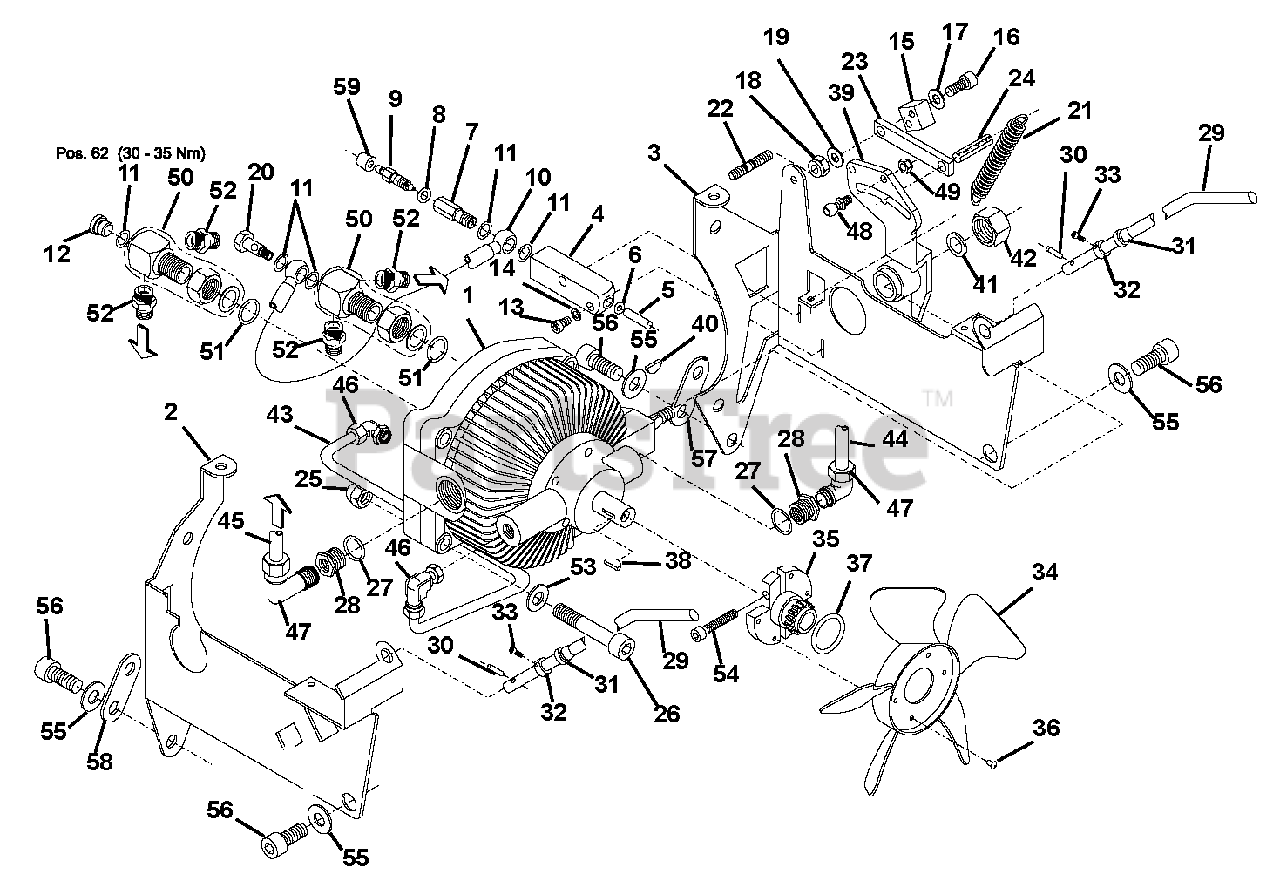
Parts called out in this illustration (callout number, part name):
1	Hydraulic Pump
2	Bracket, Left Hydrostat
3	Bracket, Right Hydrostat
4	Bushing, Guide
6	O-Ring, D3770 6,07 x 1,78
7	Bolt, Hollow Special
8	O-Ring, D3770 6.00 x 3.00
10	Hydraulic Hose
11	Ring, Gasket
12	Plug, Drain D910 Right 1/8"
13	Screw, Cylinder, D912 Metric 4 x 12
14	Washer, Form Metric 4.1/10.2 x 1.0
16	Screw, D912 Metric 6 x 12
17	Washer, M6
18	Nut, Lock, D985 M6
19	Washer, D125 6,4 x 12 x 1,6
20	Bolt, Hallow
21	Spring, Tension, 1.2/10.8 x 62
22	Stud, D939 Metric 6FO x 16
24	Pin, Heavy
25	Cap Nut, D1587 M10
26	Screw, D912 M10 x 60
27	O-Ring, D3770 199,00 x 2,40
28	Connector
29	Control Rod
30	Pin, Heavy, D1481 4 x 20
32	Adjustment Ring
33	Screw, Cylinder, D912 Metric 4 x 5
36	Rivet, Blind
37	O-Ring, D3770 28,00 x 5,00
38	Key, D6888 3/16" x 3/4"
39	Shift Rod
40	Key, Woodruff D6888 1/8" x 5/8"
41	Lock Washer, D127A M13
42	Hex Nut, 1/2"X13 UNC
43	Pipe, Hydraulic Assembly
44	Pipe, Hydraulic Assembly
45	Pipe, Hydraulic Assembly
46	Connector
47	Swivelling Screw-Fitting, XSWV
48	Joint Ball Pin
49	Nut, Lock, M6
50	Connector Assembly
51	O-Ring, D3770 199,00 x 2,40
52	Connector
53	Washer, Form Steel 10.2/20.25 x 1.6
54	Screw, Metric 8 x 35
56	Screw, D912 M10 x 25
